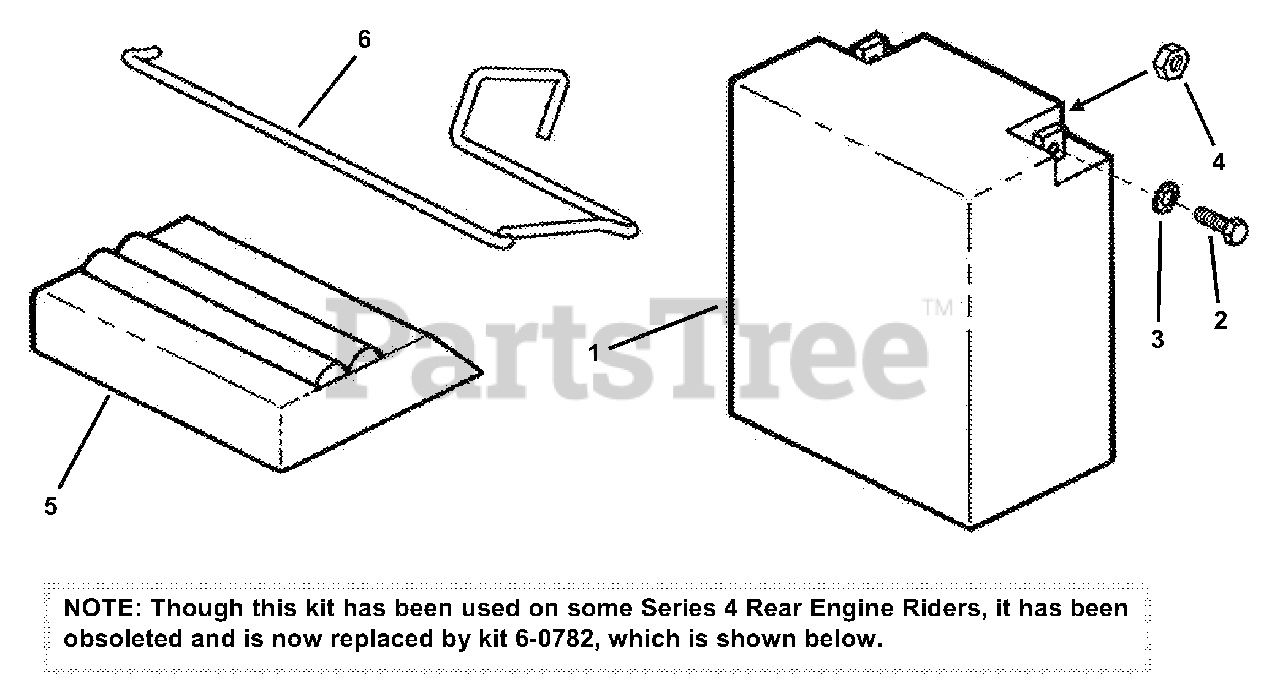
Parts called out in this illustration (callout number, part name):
1	BATTERY, Sealed Lead Acid, 6 Cell w/7 plates per cell
2	SCREW, #10-24 x 1/2" Hex Head Cap
3	WASHER, #10 External Tooth Lock
4	NUT, #10-24 Hex "Whiz Lock"
5	COVER, Battery
6	CLAMP, Battery
